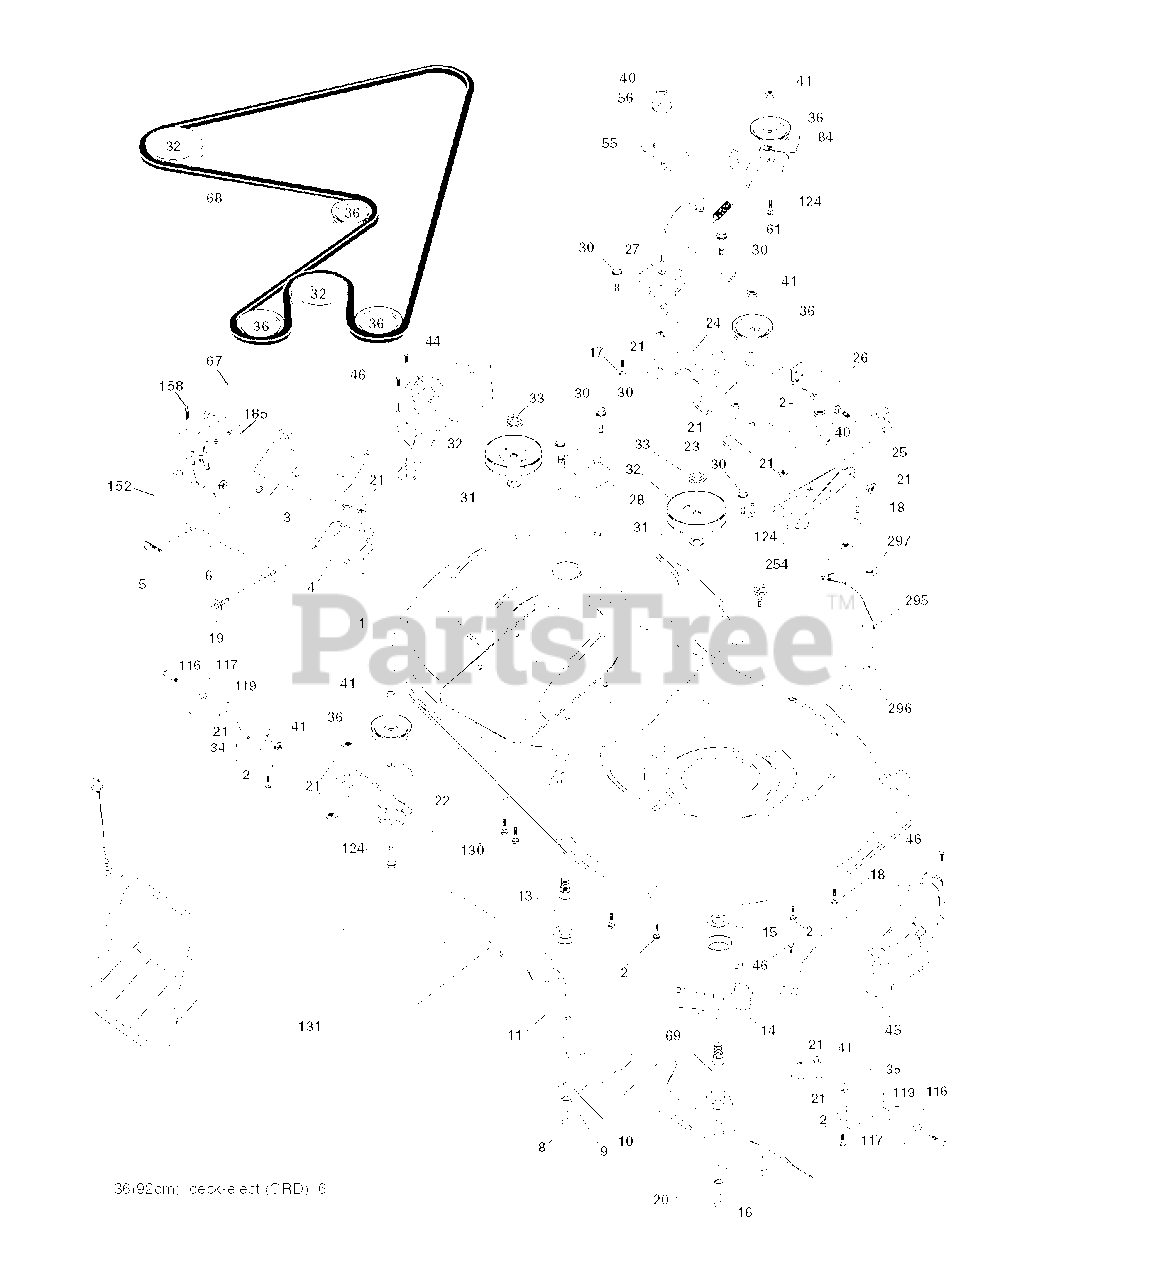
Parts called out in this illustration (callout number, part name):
2	BOLT
3	BRACKET
5	RETAINER-SPRNG RB
6	BAR SWAY
9	LOCKWASHER
10	WASHER.BLADE
13	SHAFT ASM VENT
14	HSG MANDREL
17	BOLT.3/8-14X1.25
19	BOLT SHD 5/16-18
21	LOCKNUT
24	BRACKET
25	BRACKET
28	BRACKET
30	SCREW, WASHER HEAD
31	WASHER.SPACER.MANDREL
32	PULLEY MANDREL
33	NUT.FLANGE.LOCK.TOP
36	PULLEY.IDLER.4.25
40	LOCKNUT
41	NUT LOCK FLG 3/8-16 UNC
45	MANDREL COVER
46	SCREW.1/4-20X5/8
56	SPACER.RETAINER.MOWER
67	KNOB T (3/8 HOLE)
69	SHAFT.ASM.W/LWR.BRG.RH.THREAD
84	KEEPER, BELT IDLER
117	WHEEL. GUAGE RALLY
124	BOLT.3/8-16X1.50
131	CHUTE BAGGER
158	SCREW
185	HEAD ASM. CABLE CLUTCH
254	SCREW 3/8-16X1
296	BOLT
297	NUT CENTERLOCK
